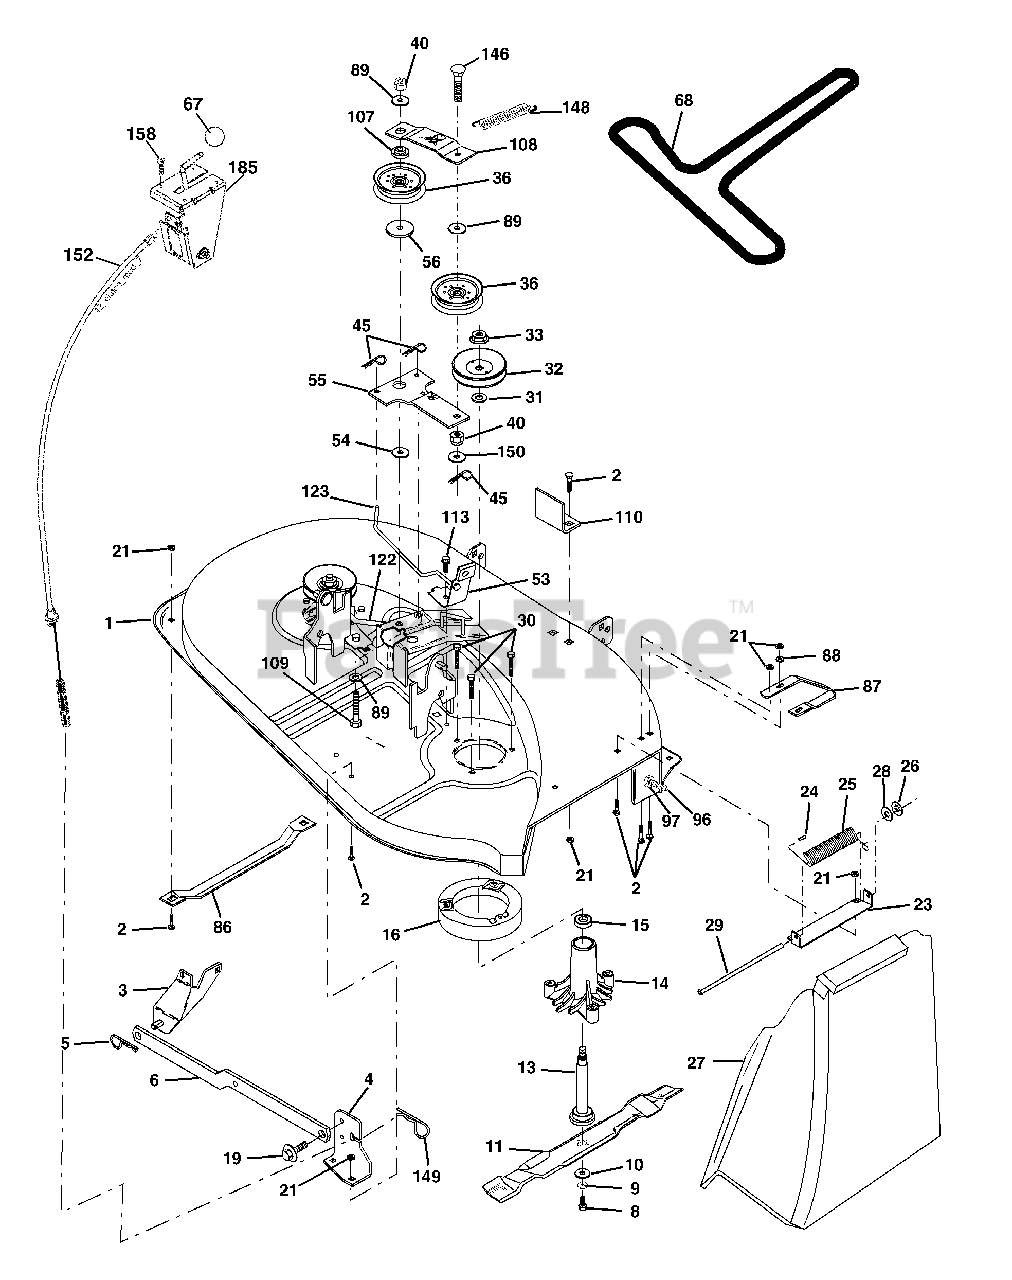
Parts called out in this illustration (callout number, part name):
1	Mower Housing Assembly
2	Bolt, Carriage 5/16-18 x 3/4
3	Bracket Asm. Fram Sway Bar
4	Bracket, Asm. Deck Sway Bar
5	Retainer, Spring
6	Bar Sway Deck
8	Bolt, Hex 3/8-24 x 1-1/4 Gr. 8
9	Washer, Lock, Hlcl Sprg 3/8
10	Washer, Hard Blade Mower Vented
11	Blade, 38" Mulching Std
11	Blade, 38" Mulching Premium
11	Blade, 38" Hi-Lift
13	Shaft and Bearing Assembly
14	Mandrel Housing, Vented
15	Ball Bearing, Mandrel
16	Stripper, Mower, Vented
19	Bolt, Shoulder
21	Nut, Crownlock 5/16-18
23	Bracket, Mower Deflector
24	Cap, Sleeve
25	Spring, Deflector
26	Nut, Push
27	Shield, Deflector
28	Washer 11/32 x 3/4 x 16 Ga.
29	Rod, Hinge
30	Screw, Thdro
31	Washer, Spacer
32	Pulley, Mandrel
33	Nut, Flangelock 9/16
36	Pulley, Idler, Flat
40	Nut Crownlock 3/8-16
45	Retainer, Spring
53	Brake Assembly
54	Washer Hardened
55	Idler Arm Assembly
56	Spacer, Retainer
67	Knob
68	Belt
86	Runner, LH
87	Runner, RH
88	Washer 11/32 x 3/4 x 16 Ga.
89	Washer 13/32 x 13/16 x 11 Ga.
96	Bolt 3/8-16 x 1-1/4
97	Nut Centerlock 3/8-16
107	Spacer, Retainer
108	Stiffener, Idler Arm
109	Bolt, Hex Head 3/8-16 x2-1/2
110	Upstop Deck Front 38"
113	Screw 5/16-18 x 3/4
122	Rod, Brake, LH
123	Rod, Brake, RH
146	Bolt Carriage Idler
148	Spring Return Idler
149	Retainer Spring Yellow Zinc
150	Washer 9/32 x 3/4 x 10 Ga.
152	Cable Clutch 38 In
158	Screw Hex Thd Cut 1/4-20 x 1/2
185	Head Asm. Cable Clutch
